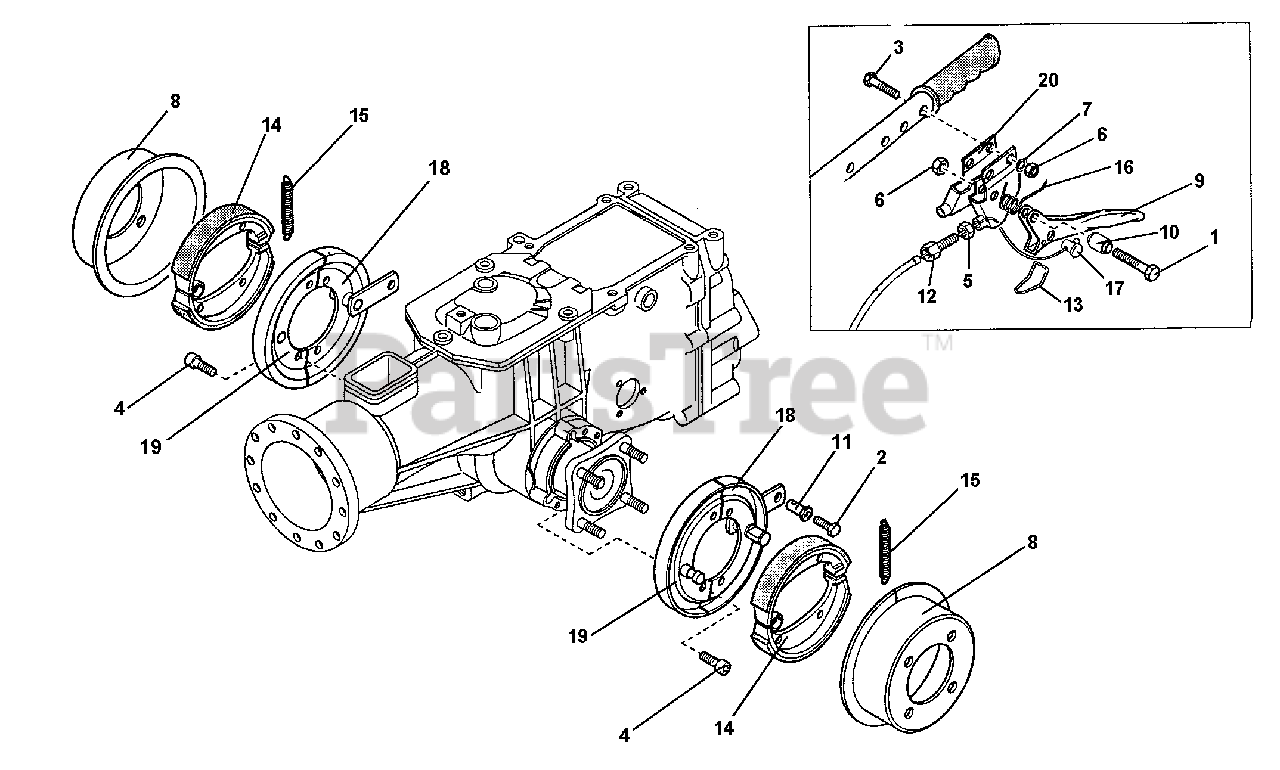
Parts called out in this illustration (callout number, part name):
1	SCREW, M6X25
2	SCREW, M6X16
3	SCREW, M6X35
4	SCREW, M8X25
6	NUT, SELF LOCKING, M6
7	WASHER, LOCK, M6.4
10	LEVER SPACER
11	PIN, CABLE CLAMP
12	SCREW, ADJUSTING, M8
16	LEVER SPRING
18	SEMIDISC LEVER
19	PIN, HALF DISC
20	COUPLING FOR DOUBLE LEVER
